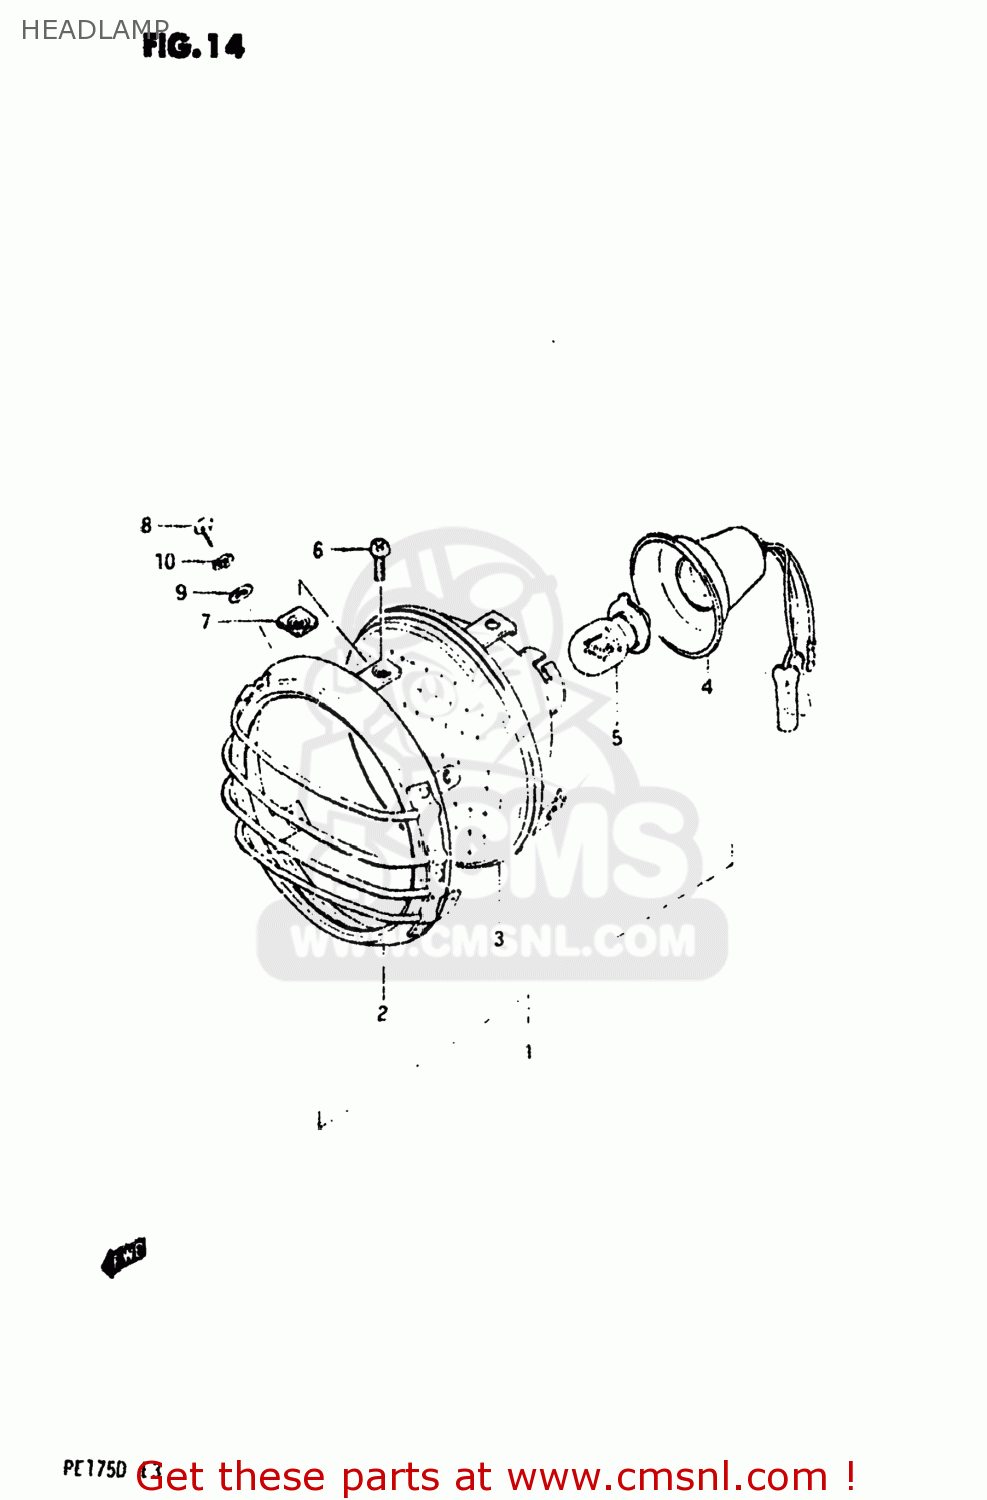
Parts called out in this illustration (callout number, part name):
1	LAMP ASSEMBLY,HEAD
2	RIM,HEADLAMP
3	LAMP UNIT
4	SOCKET,HEADLAMP
5	BULB(6V15/15W/STANLEY,A3598HA)
6	SCREW
7	NUT
8	SCREW
9	WASHER
10	LOCK WASHER
